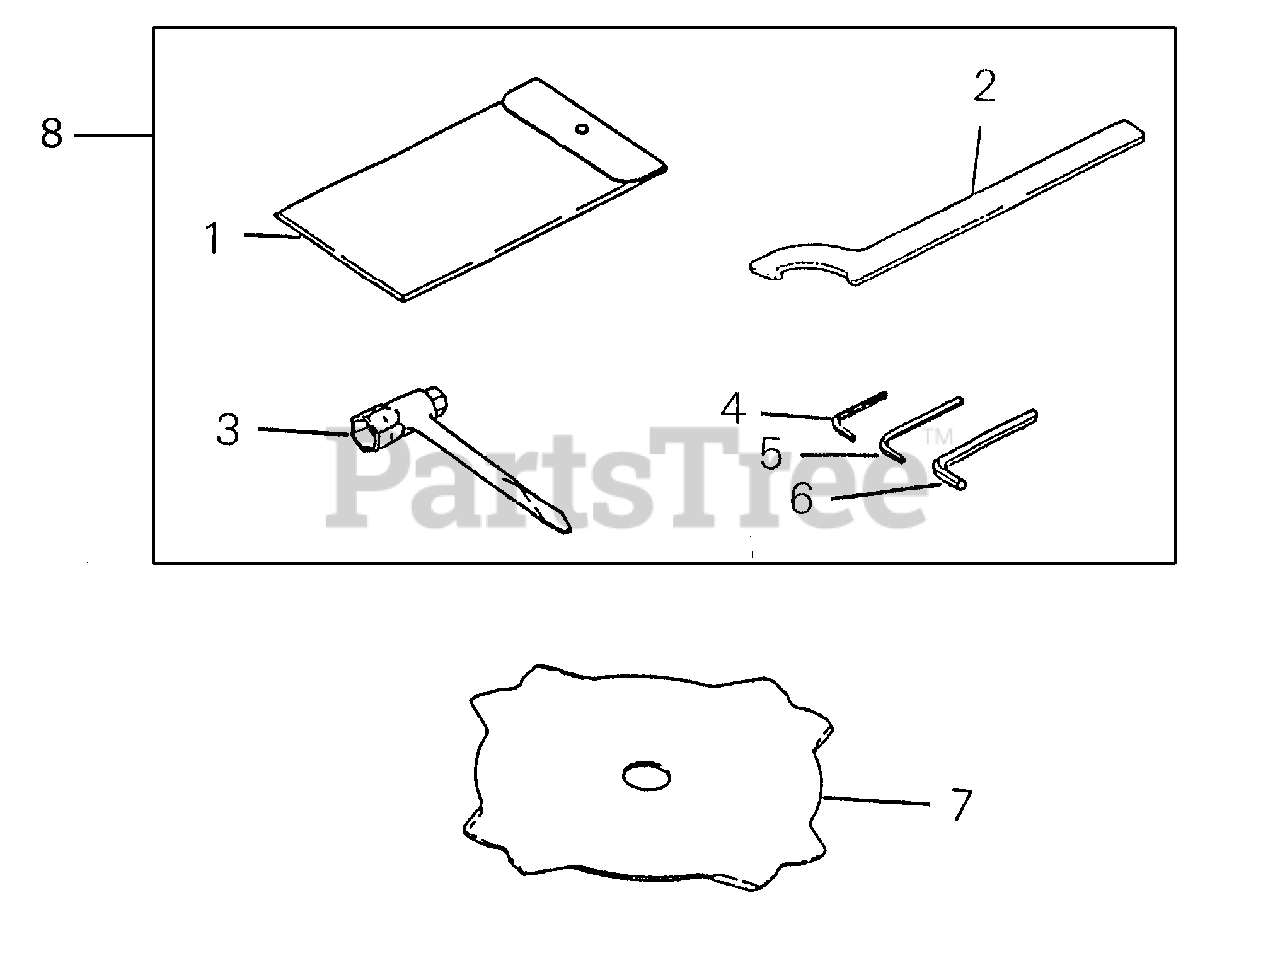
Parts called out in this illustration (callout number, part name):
1	BAG, TOOL
2	HOOK SPANNER
3	T-WRENCH - 13X19mm
4	HEX KEY - 3mm
5	HEX KEY - 4mm
6	HEX KEY - 6mm
7	BLADE - 8 TOOTH -- 10" (25cm)
8	TOOL KIT
